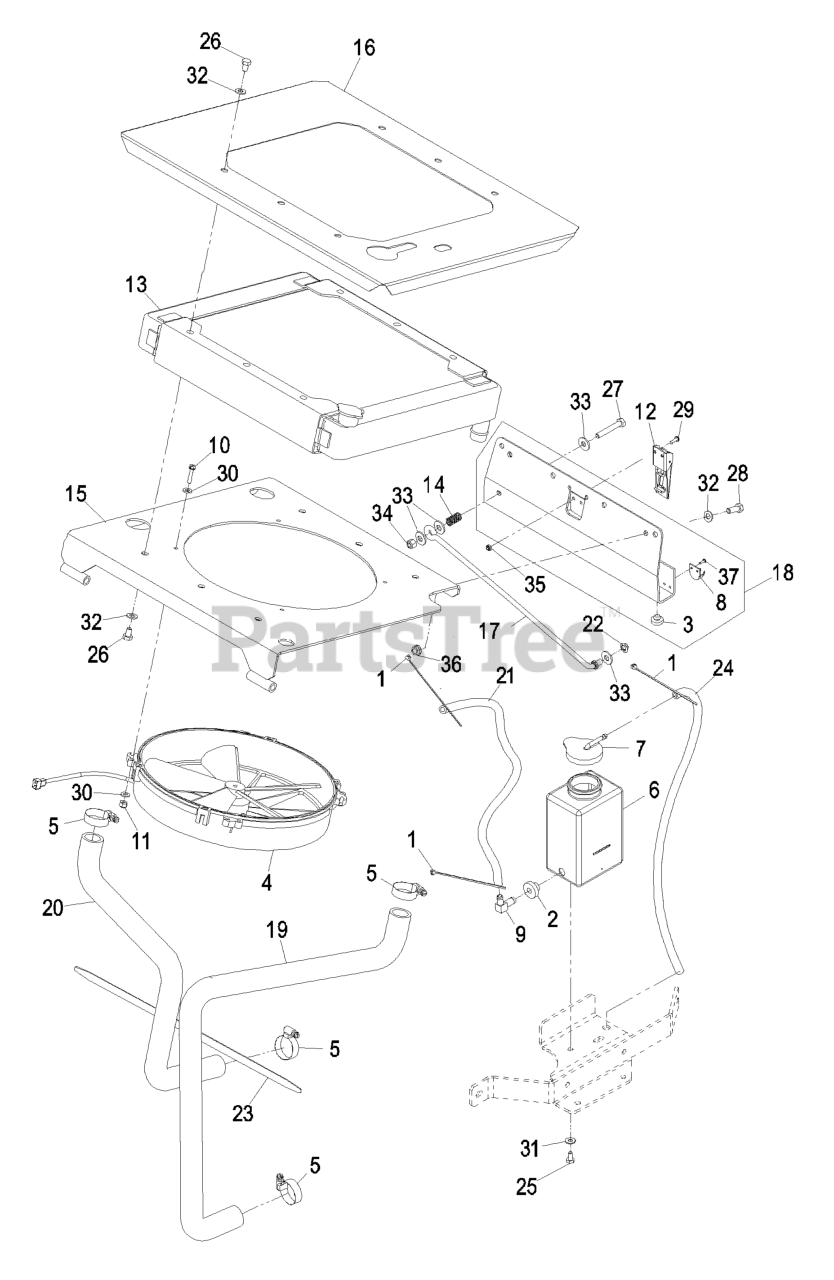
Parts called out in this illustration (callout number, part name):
1	TIE-CABLE
6	TANK-OVERFLOW
7	CAP-TANK, OVERFLOW
11	NUT-LOCK, HH
12	LATCH-CAMLOC
13	RADIATOR-MOUNT
14	SPRING,LOCK PIN
17	ROD,PROP
20	HOSE, RADIATOR
21	HOSE, OVERFLOW
25	SCREW-HH
26	SCREW-HH
27	SCREW-HH
28	SCREW-HH
29	SCREW-PPH
30	WASHER-FLAT
31	WASHER-FLAT
32	WASHER-PLAIN
33	WASHER-FLAT
34	NUT-LOCK, NI
35	NUT-LOCK
